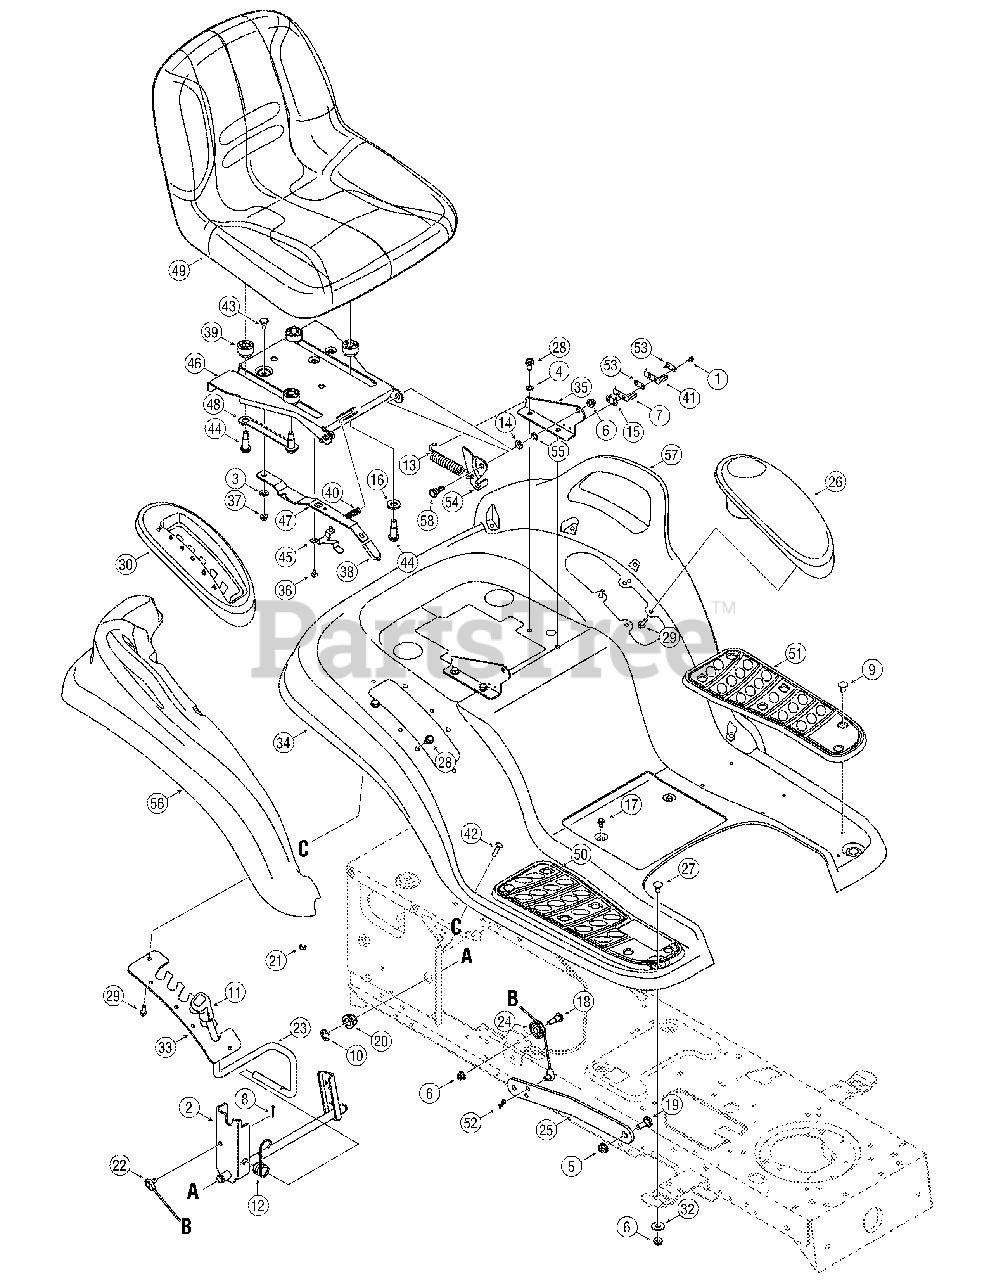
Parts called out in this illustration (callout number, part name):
1	Screw, #8-18 x.500
4	Lock Washer, 5/16
5	Flange Lock Nut, 3/8-16
6	Flange Lock Nut, 5/16-18
7	Inner Seat Spring Switch
8	Hairpin Clip
9	Foot Pad Clips
12	Torsion Spring
13	Extension Spring,.84 x 4.6
15	Insulator Boss Plate
16	Flat Washer,.31 x 1.062 x.134
17	Screw, 1/4-20 x.500
18	Hex Cap Screw, 5/16-18 x.62
19	Shoulder Screw, 3/8-16
20	Hex Flange Bearing
21	Sems Nut 1/4-20
22	Lift Cable, 16.16
24	Roller Pulley
26	Cover w/ Cup Holder
27	Carriage Bolt, 5/16-18 x.750
28	Self-tapping Screw, 5/16-18 x.625
29	Self-tapping Screw, 1/4-15 x.75
30	Lift Lever Cover
31	Shoulder Screw,.437 x.286
32	Flat Washer,.349 x 1.0 x.063
36	Screw, #10-16 x.375
37	Flange Lock Nut, 1/4-20
38	Seat Adjuster Grip
40	Compression Spring,.41 x 1.5
41	Outer Seat Spring Switch
42	Carriage Screw 1/4-20 x 1.00
43	Shoulder Screw,.340 x.285,1/4-20
44	Shoulder Screw,.50 x.50, 3/8-16
48	Seat Adjustment Selector
49	High Back Seat, Black
53	Insulator Plate
54	Seat Lift Bracket
56	RH Fender Flare
57	LH Fender Flare
